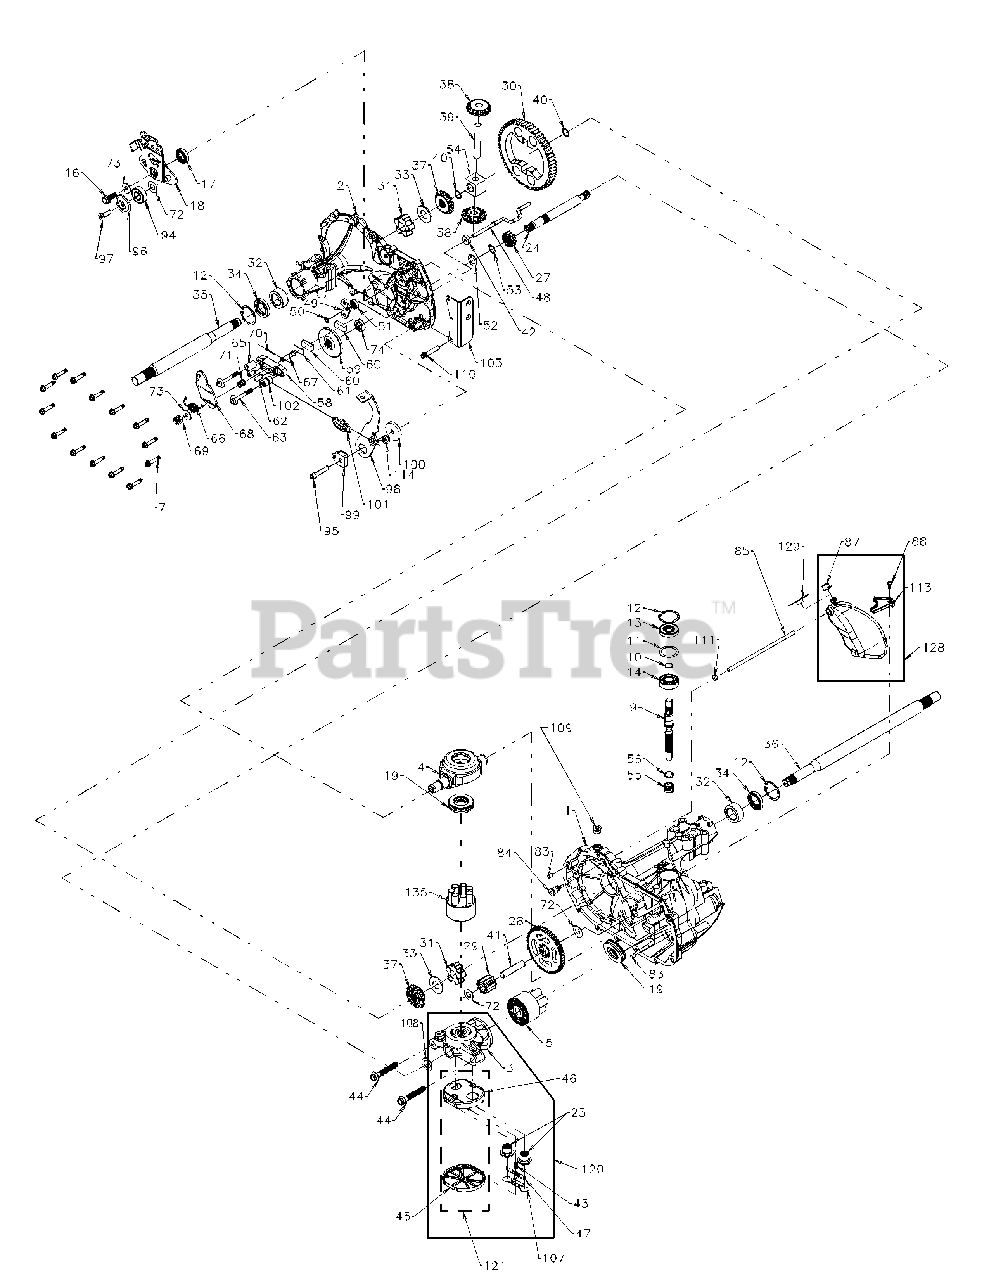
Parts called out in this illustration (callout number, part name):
1	Main Housing, Assembly, Black
2	Side Housing, Assembly, Black
3	Center Section, Assembly
4	Swashplate, Trunnion Machined
5	Block - Assembly
7	Hex Flange Screw 1/4-20 x 1.25
9	Shaft, Input
10	Ring - Retaining
12	Ring - Retaining
13	Seal, Lip .67 x 1.58 x .276
14	Ball Bearing 17mm x 40mm x 12mm
16	Hex Flange Hd. Screw 5/16-24 x 0.75
17	Lip Seal 18 x 32 x 7
18	Arm, Control
19	Bearing, 30 x 52 x 13 Thrust
23	Check Plug Ass'y, .027, Washer
24	Shaft, Motor
27	Gear - Pinnion, 13t
28	10t / 48t Gear
29	Gear, 10t Jackshaft
30	60t Bull Gear
31	Sleeve Bearing .75 x 1.750 x .625
32	Sleeve Bearing 1.00 x 1.575 x .625
33	Washer, 3/4 ID x 1-1/2 OD x .13
34	Lip Seal Axle Seal
35	Shaft, Axle 1.00 x 11.99 Flange
36	Shaft, Axle 1.00 x 17.59 Flange
37	Miter Gear (Splined)
38	Miter Gear 15t (0.5 ID)
40	Ring, Spiral Retaining
41	Pin, Jackshaft
42	Magnet, Ring
43	Spring, Bypass
44	Hydro Mounting Screw 3/8-24 x 2.5 Lg
45	Filter
46	Base, Filter
47	Actuator, Bypass
48	Rod, Bypass Actuator
49	Arm, Bypass
50	Retaining Ring 0.250 External
51	Seal, Lip .741 x .250 x .250 Tc
52	Flat Washer, 5/8 ID x 1.0 OD x .05
53	Retaining Ring
54	Bearing, Center Block
55	Spring - Helical Compression
57	DSO Fluid (Gal)
58	Brake Yoke
59	Rotor, Brake
60	Brake Puck
61	Puck Plate
62	Brake Actuating Pin
63	Bolt, Special Flange, 1/4-20 x 2 w/patch
66	Spring, Brake Arm Bias
67	Square Head Bolt 5/16-24- Ribbed
68	Arm, Brake
69	Slotted Hex Nut 5/16-24
70	Cotter Pin 3/32 x 3/4
71	Compression Spring Brake Anti-drag
72	Washer, Ht .5 ID x 1 OD x .032
73	Flat - Washer 11/32 ID x 7/8 OD
74	Oil Seal .625 x 1.0 x.25
83	Pin, Standard Headless
84	Fitting, 5/16 Sae 5/32 Tube
85	Hose, Expansion Tank
87	Cap, Vent
88	Bolt, Self Tapping 10-32 x 1/2
94	Ball Bearing .62 ID x 1.38 x .44
95	Socket Head Screw, 5/16-24 x 1-1/2
96	Spacer, Locating
98	Arm, Return
99	Puck, Adjusting
100	Washer, .325 OD x 1.60 ID x .150
101	Spring, Extension
102	Spacer .560 OD x .260 ID x .870
103	Bracket, Torque
107	Deflector
108	Washer, Shaft .71 x 1.15 x .030
110	Torx Head Screw, 5/16-18
111	O-ring .07 x .301 ID
113	Bracket,support Expansion Tank
114	Spring Guide
120	Center Section-Filter-Bypass Ass'y
121	Filter Assembly
122	Seal - O-ring Kit
128	Kit, Expansion Tank
135	Block, Assembly 7 Piston
